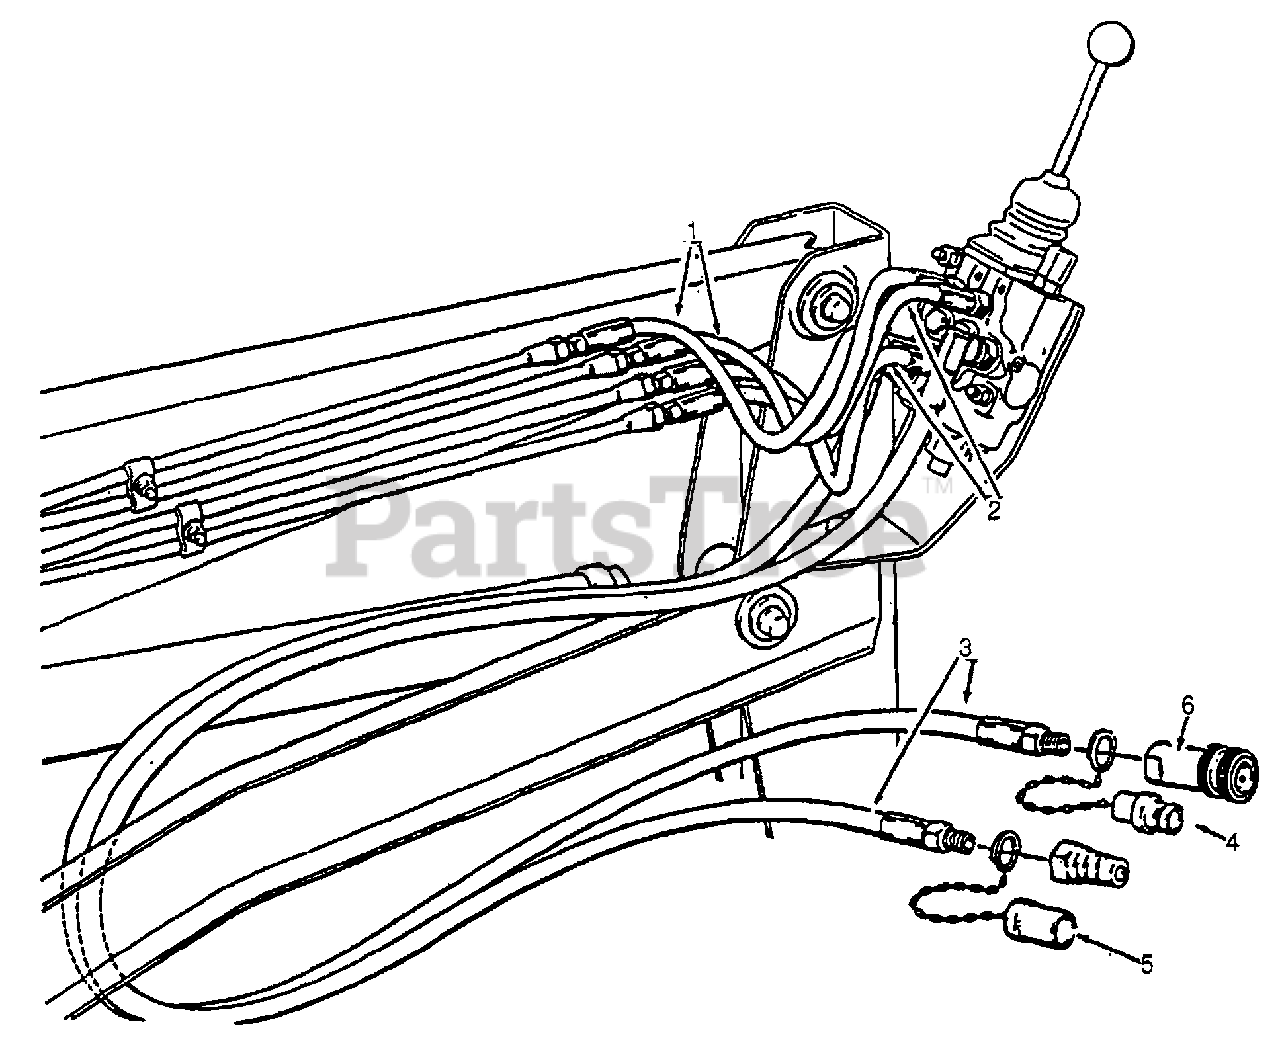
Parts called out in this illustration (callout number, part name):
1	HOSE, HYDRAULIC (1/4X20") (NOT AVAILABLE)
2	HOSE, HYDRAULIC (1/4X18")
3	HOSE, HYDRAULIC (3/8X38") (NOT AVAILABLE)
4	PLUG ASSY., DUST
5	CAP ASSY., DUST
6	DISCONNECT ASSY., QUICK
NI	FITTING, ADAPTER (3/8NPTX3/8NPT) (90) (NOT AVAILABLE)
